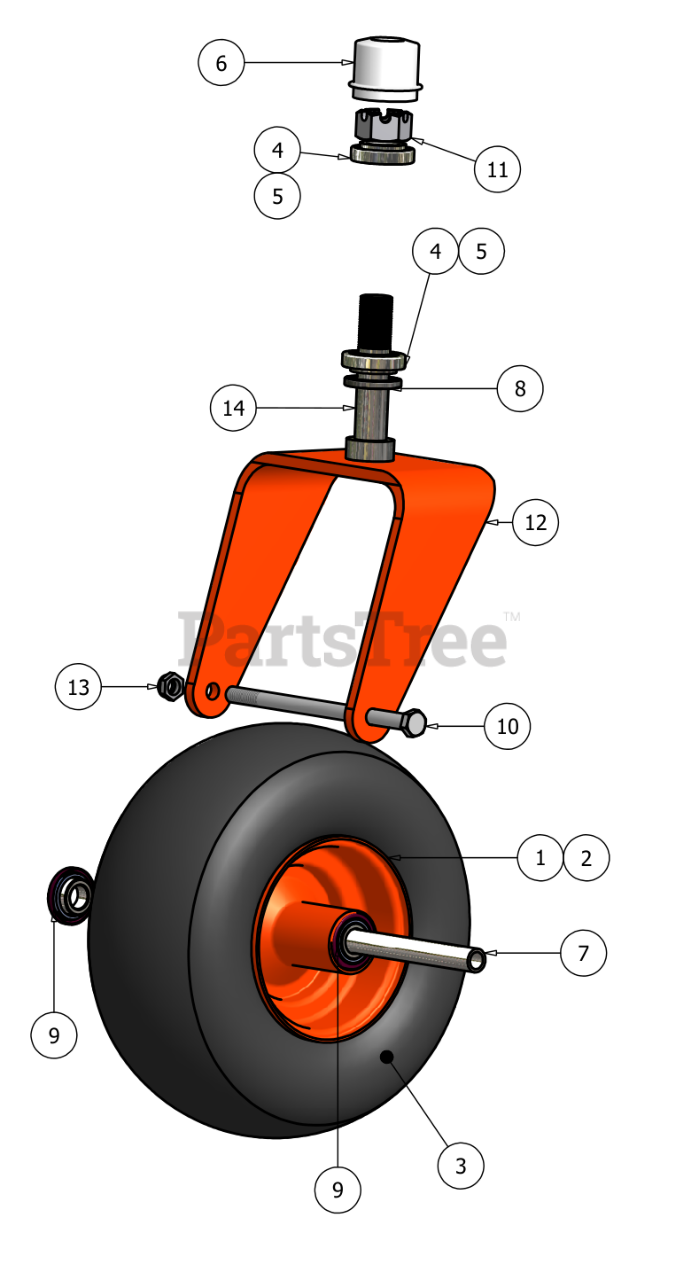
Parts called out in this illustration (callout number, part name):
1	13 x 6.50 -6 Tire and Wheel Assembly
2	13" x 6.50 6" Tire
3	6" Wheel ONLY
6	Dust Cover
7	Front Wheel Spacer
9	Wheel Bearing
10	1/2" x 9" Bolt
11	1" Fine Threaded Castle Nut
12	Front Fork with Spindle
13	5/8" Nylock (1/2 Jam)
14	Front Fork Spindle
